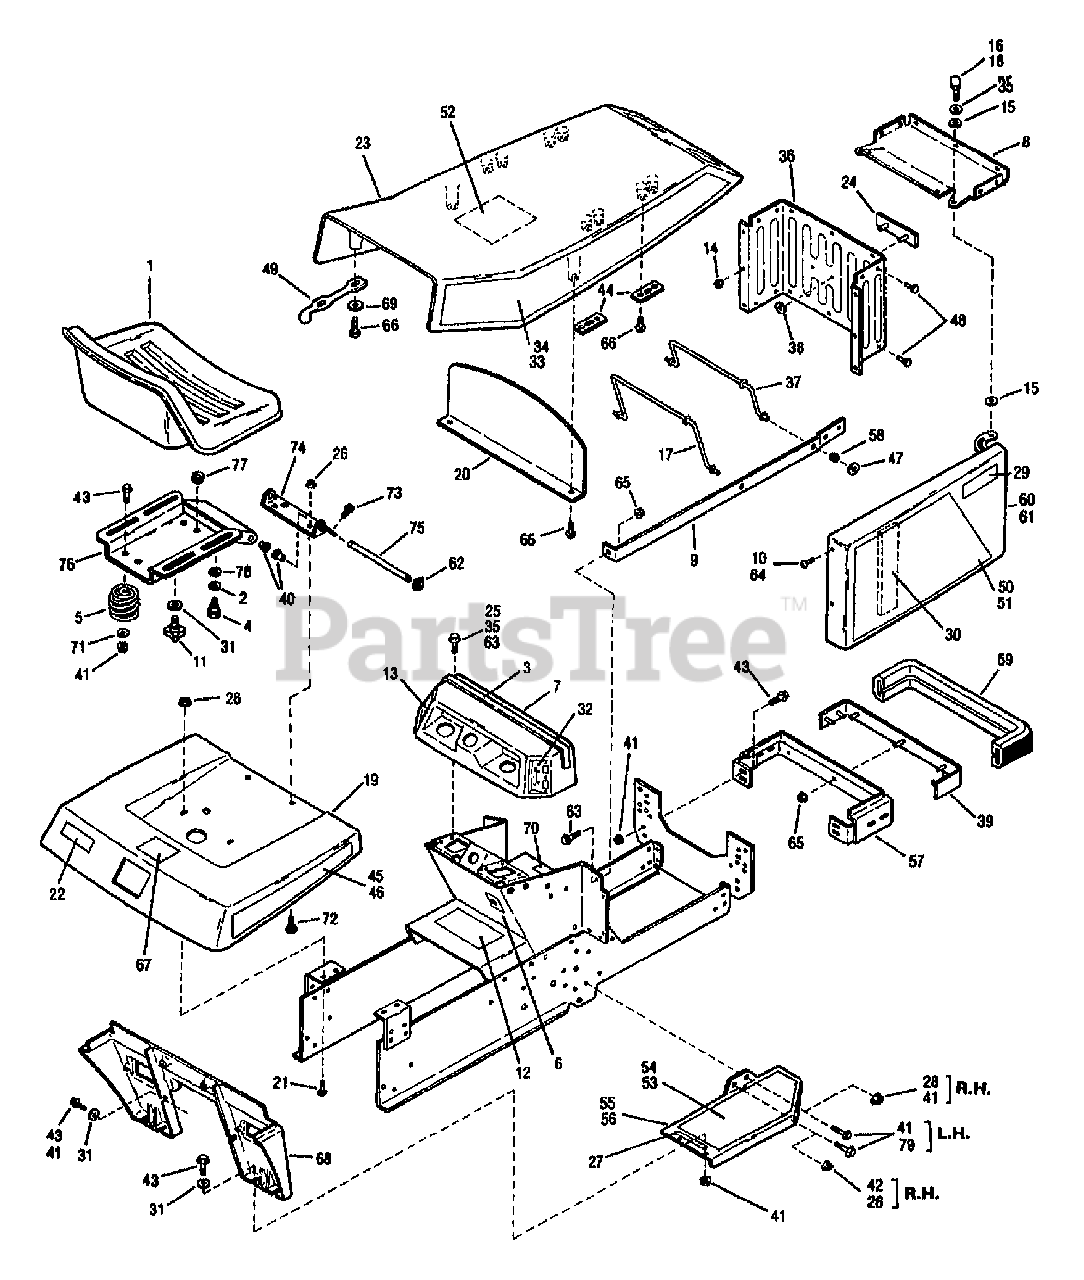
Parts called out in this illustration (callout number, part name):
2	WASHER-1.06X.51X.09 NYLON
3	PAD-HOOD
4	SCR-SHLDR 3/8-16X.25 G5ZP
5	SPRING-COMPRESSION
6	DECAL-IGNITION
7	PANEL-INST
8	CAP-GRILLE
9	SUPPORT
10	NUT-SPEED #10
12	DECAL-INSTRUCTIONS
13	DECAL-CHOKE
14	NUT W/LKWASHER 10-24 ZP
15	WASHER
16	SCR-HH 1/4-20X.75 G5 ZP
17	LINK-HINGE
18	NUT-HT LK 1/4-20
20	BAFFLE-HOOD
21	SCR-CARR 5/16-18X.75 G2 ZP
22	DECAL-LOGO
24	PLATE-LOGO
25	NUT-HF/LK 1/4-20 ZP
26	NUT-HFLK 5/16-18 ZP
27	CUSHION
28	SCR-HH 3/8-16X.75 G5 ZP
29	DECAL-HYDRO
30	BLOCK-SEALING
31	WASHER-.986X.437X.083 ZP
32	DECAL-THROTTLE
33	DECAL-HOOD LH
34	DECAL-HOOD RH
35	WASHER-FLAT 1/4 SAE
37	LINK-HINGE
38	NUT-PUSH
39	ASSM-BUMPER STRAP
41	NUT-HFLK 3/8-16 ZP
42	SCR-TRUSS HD 5/16-18X.62
43	SCR-HFLK 3/8-16X1.00 ZP
44	RETAINER-HINGE LINK
45	DECAL-RH
46	DECAL-LH
47	RETAINER
48	RIVET-POP
49	LATCH-RUBBER
50	DECAL-SIDE COVER LH
51	DECAL-SIDE COVER RH
52	DECAL-SVC INST
55	FOOTREST-LH
56	FOOTREST-RH
57	ASSM-GRILLE SUPT
58	GROMMET
59	BUMPER-EXTRUSION
62	RING-RET."E" .300 ID
63	SCR-HH 1/4-20X.625
64	SCR-TRUSS #10-24 X 5/8
65	NUT-HF/LK 1/4-20 ZP
66	SCR-SEMS MACH
67	DECAL-FUEL
68	SUPT-RUNNING BOARD
70	DECAL-WARNING
71	WASHER-FLAT 1.25X.406X.179
72	BOLT-CARR 5/16-18X.63 ZP
73	SCR-HFLK 5/16-18X.75 ZP
74	BRACKET
76	ASSM-SEAT SUPPORT
